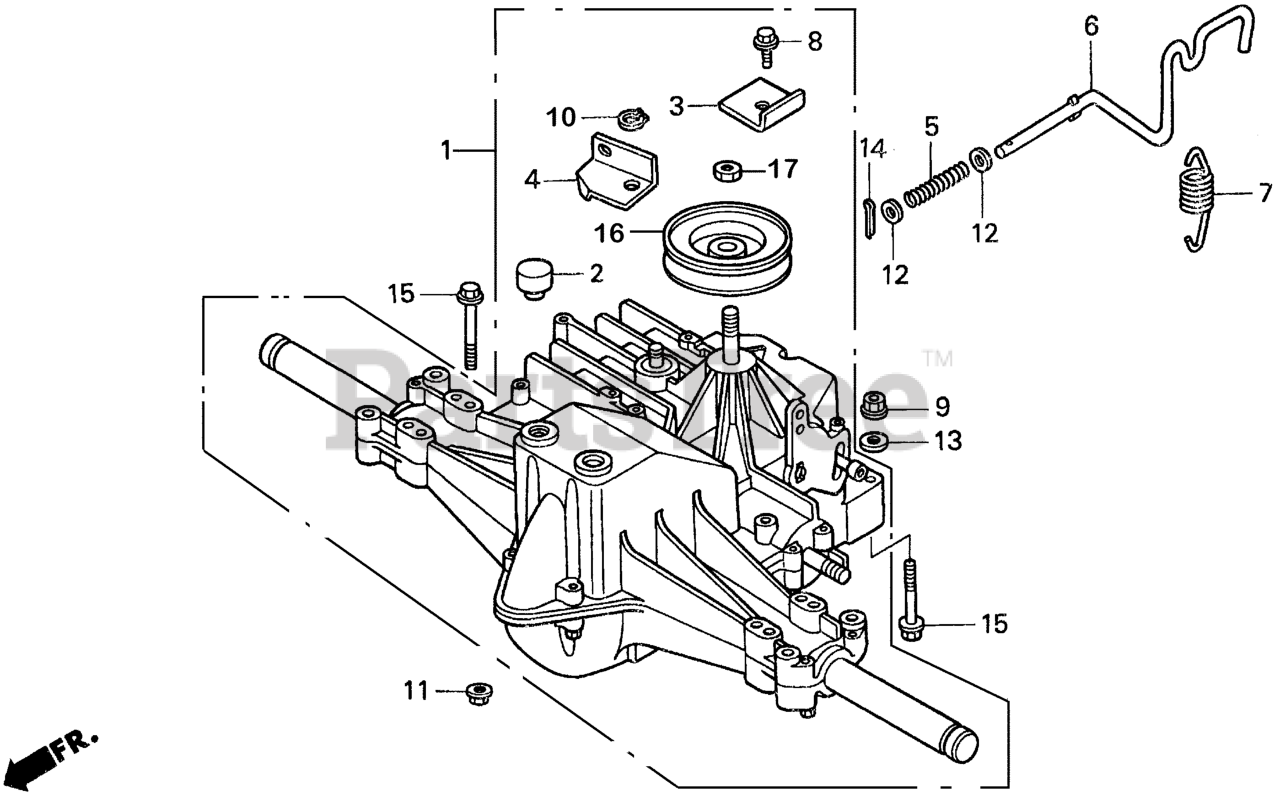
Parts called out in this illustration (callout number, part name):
1	TRANSMISSION ASSY.
2	BREATHER ASSY.
3	STOPPER, BRAKE ARM
4	PLATE, NEUTRAL VALVE (BYPASS)
5	SPRING, NEUTRAL VALVE LEVER
6	LEVER, NEUTRAL VALVE
7	SPRING, NEUTRAL VALVE RETURN
8	SCREW (1/4-20X1/2)
9	NUT, FLANGE (8MM)
10	RING, RETAINING
11	NUT, FLANGE (8MM)
12	WASHER, PLAIN (6MM)
13	WASHER, PLAIN (8MM)
14	PIN, COTTER (2.5MM)
15	BOLT, FLANGE (8X60)
16	PULLEY, TRANSMISSION
17	NUT, HEX. (1/2-20UNF)
NI	CONTROL ARM KIT (REPAIR KIT FOR BROKEN SPEED
